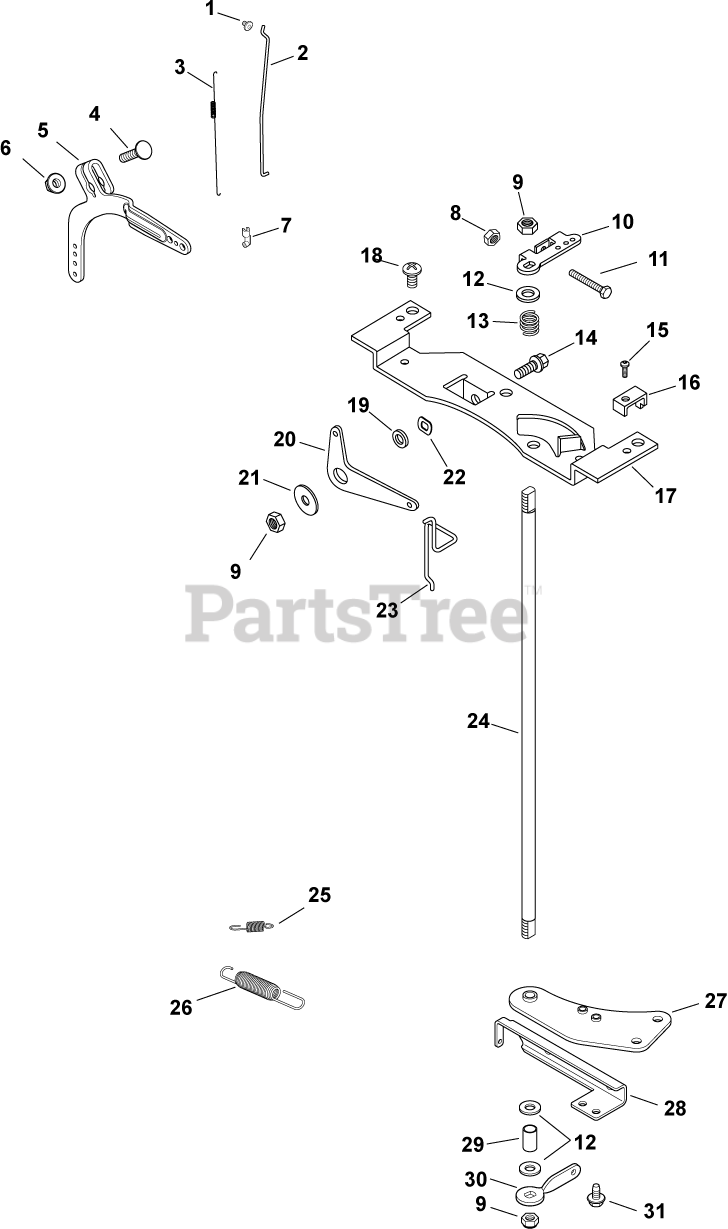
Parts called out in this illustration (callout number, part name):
1	BUSHING, LINKAGE RETAINING
2	LINKAGE, THROTTLE
3	SPRING, LINKAGE
4	BOLT, RD HD SQ NECK M6X1.0X25
5	LEVER, GOVERNOR-USE 24 090 57-S
6	NUT, FLG M6X1.0
7	BUSHING, THROTTLE LINKAGE
8	NUT, M4X0.7
9	NUT, LOCK M6X1.0
10	LEVER, THROTTLE CONTROL
11	SCREW, CAP M4X.7X30
12	WASHER, FLAT 1/4"
13	SPRING, THROTTLE SHAFT
14	SCREW, FLG M6X1.0X16
15	SCREW,FLG THD FRM M5X0.8X16-(#25086398S)
16	CLAMP, CABLE
17	BRACKET, CONTROL-USE 24 126 219-S
18	SCREW, PHL HD 11-16X3/4"
20	LEVER, CHOKE
21	WASHER, FLAT 1/4"
22	WASHER, SPRING 3/8"
23	LINKAGE, CHOKE
24	SHAFT, THROTTLE
25	SPRING, GOVERNED IDLE
26	SPRING, GOVERNOR (RED)
27	BRACKET, THROTTLE SHAFT
28	BRACKET, GOVERNED IDLE
30	LEVER, THROTTLE CONTROL
31	SCREW, FLG THD FRM M5X.8X10
